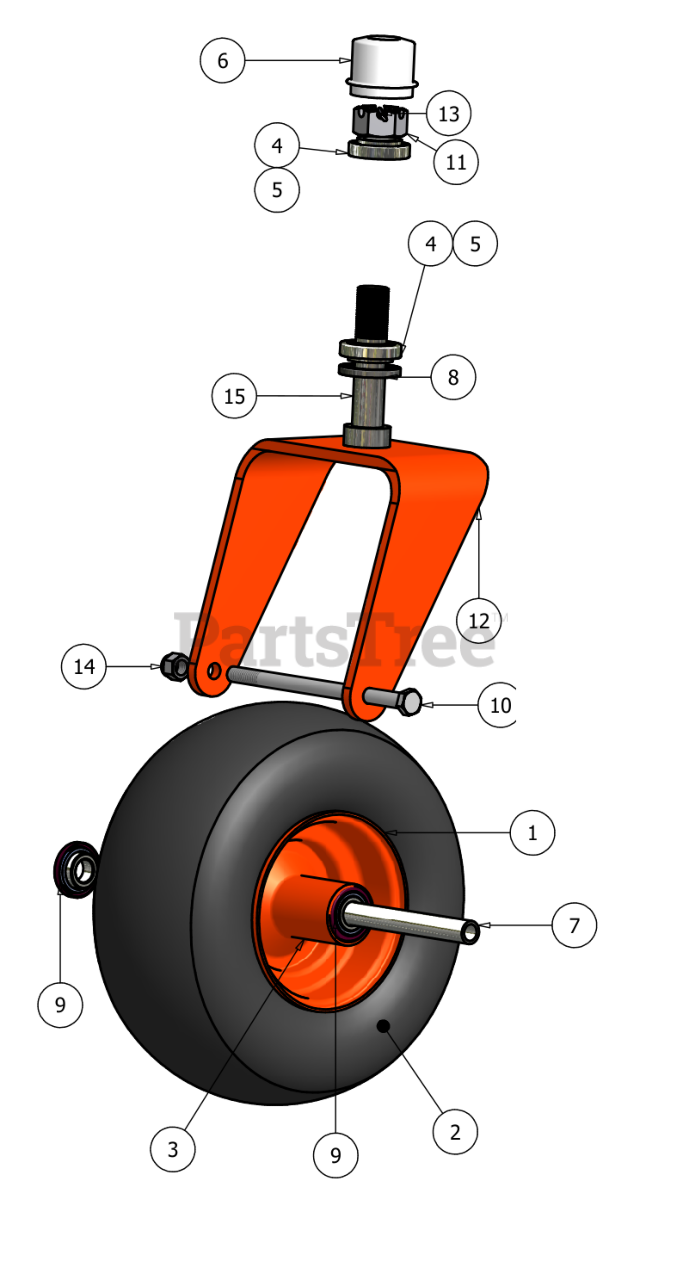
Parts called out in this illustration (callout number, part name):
1	13" x 6.50 -6" Tire
2	13" x 6.50 -6" Tire
3	6" Wheel ONLY
6	Dust Cover
7	Front Wheel Spacer
9	Wheel Bearing
10	1/2" x 9" Bolt
11	1" Fine Threaded Castle Nut
12	Front Fork with Spindle
13	1/8" x 2 1/4" Cotter #8
14	1/2" Nylock Nut
15	Front Fork Spindle
